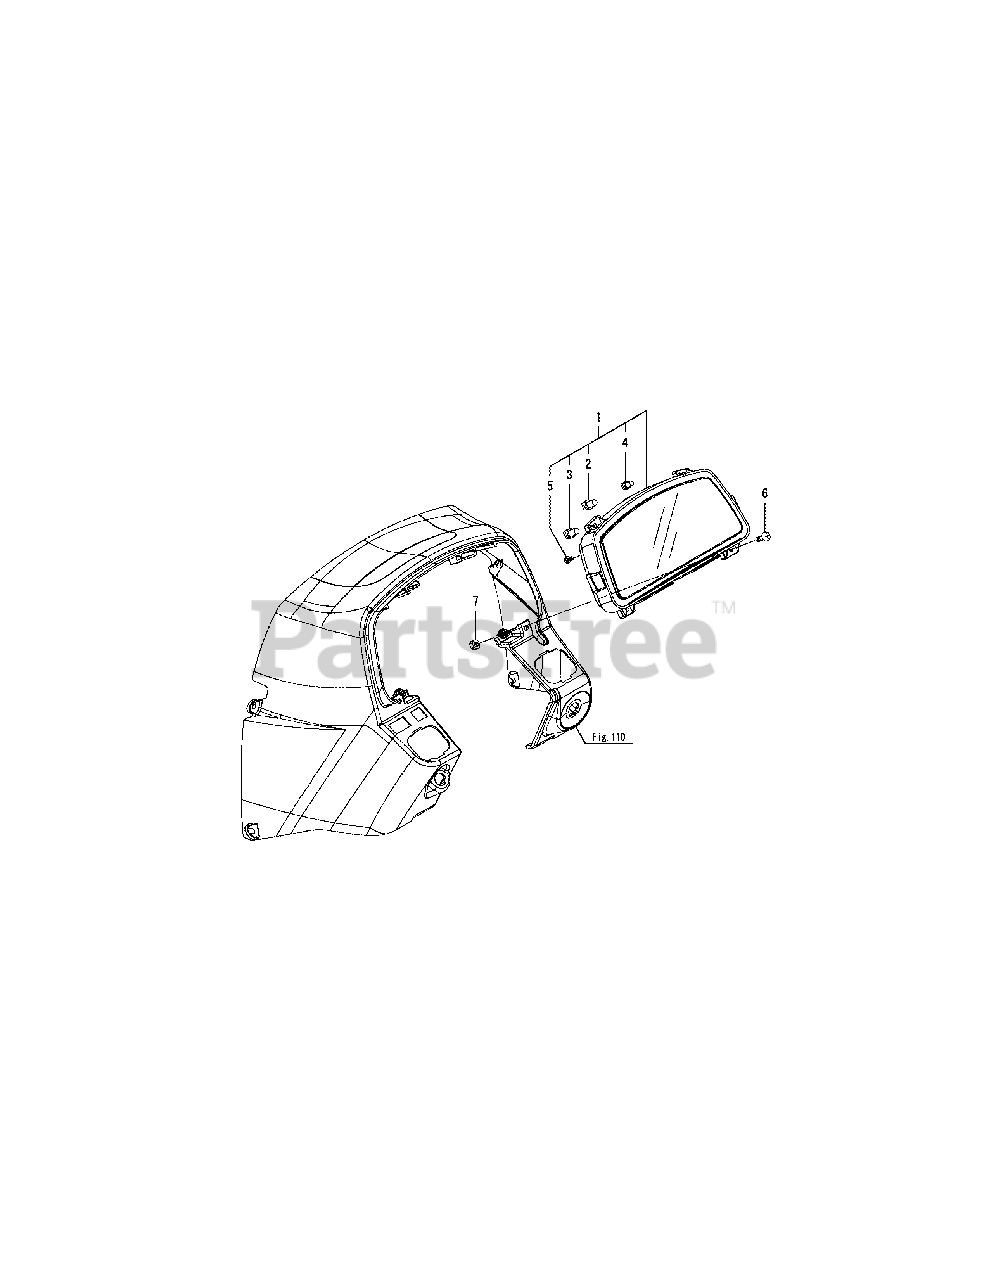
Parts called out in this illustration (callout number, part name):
2	LAMP ASSY.,SOCKET
3	BULB, 14V-1.7W
4	LAMP 14V/1.4W,SOCKET
